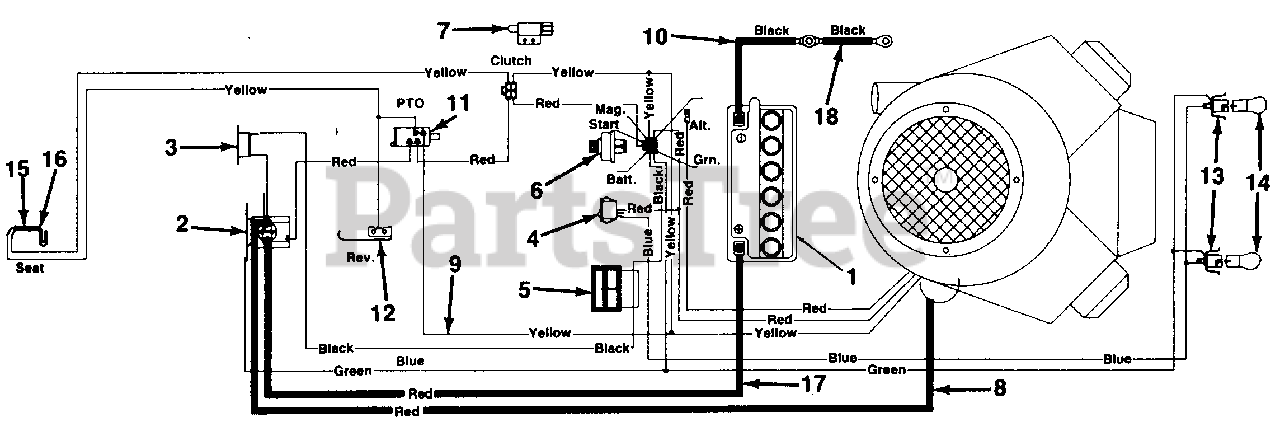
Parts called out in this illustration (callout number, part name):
1	Battery-1 2V
2	Solenoid
3	Circuit Breaker
4	Light Switch
5	Ammeter
6	Ignition Switch
7	Safety Switch
8	Electric Wire-30.0" Lg.
9	Wire Harness
10	Ground Wire-11.5" Lg.
11	Safety Switch
12	Safety Switch
13	Headlight Socket
14	Headlight Bulb
15	Safety Switch
16	Safety Switch
17	Electric Wire-27" Lg.
18	Ground Wire-7.5" Lg.
